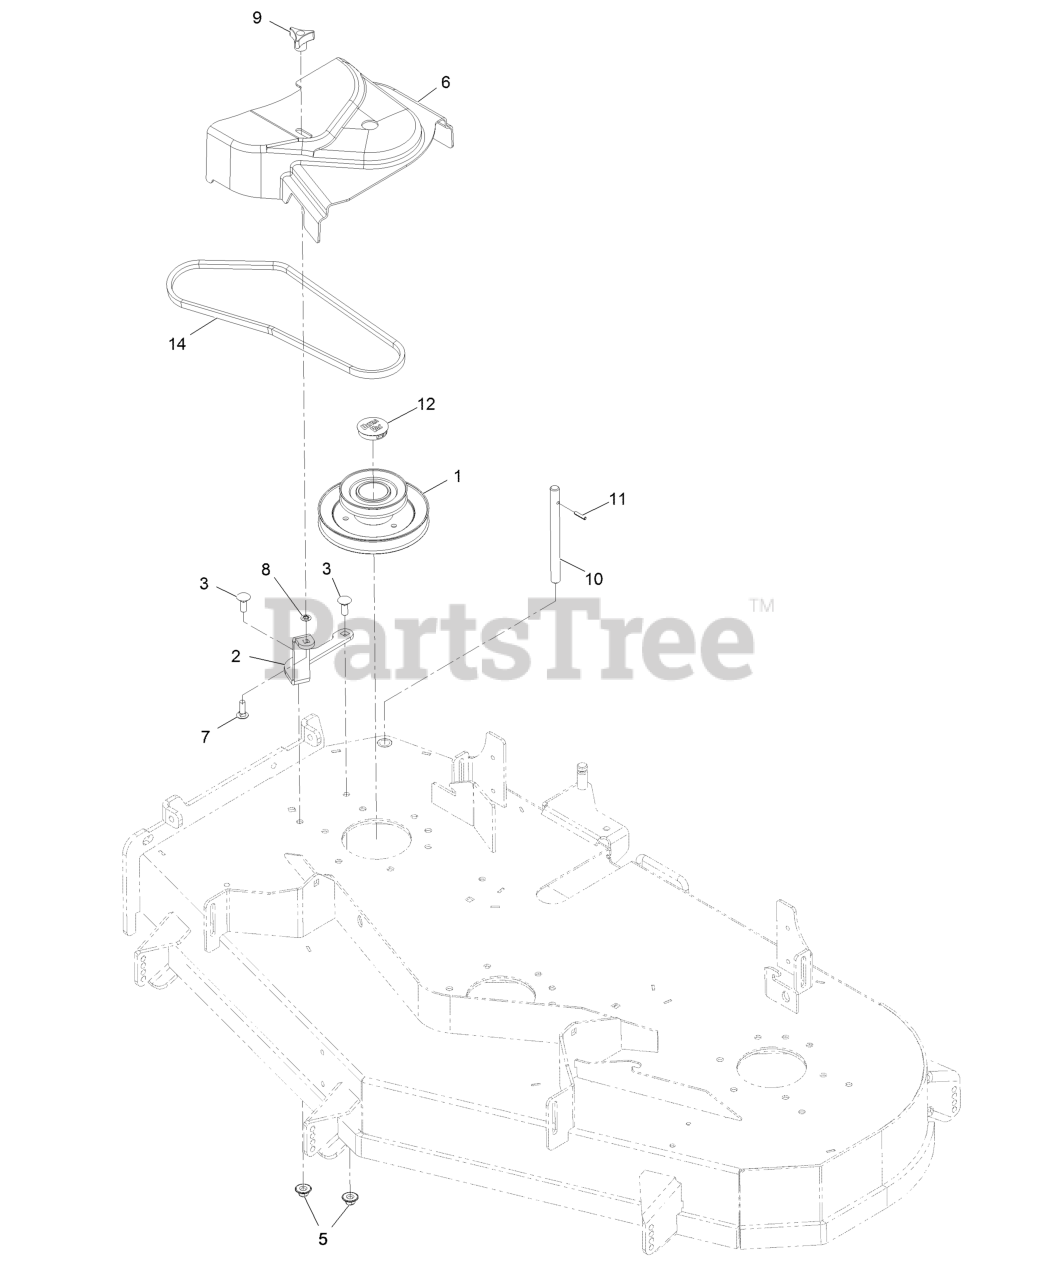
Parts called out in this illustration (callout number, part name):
1	JACKSHAFT,UV DRIVE 524 SP
2	BRACKET, SMALL UV BELT CO
3	BOLT-CARR
5	Nut-Nyloc 3/8-16 Flg
6	COVER-BELT, UV 52
7	BOLT-CARR
8	RING-RETAINING, BOLT
9	KNOB-3 PRONG
10	SHAFT-CATCHER, GRASS
11	PIN-ROLL
12	PLUG, BLACK NYLON 1.75
14	BELT, BLOWER 52"DECK
